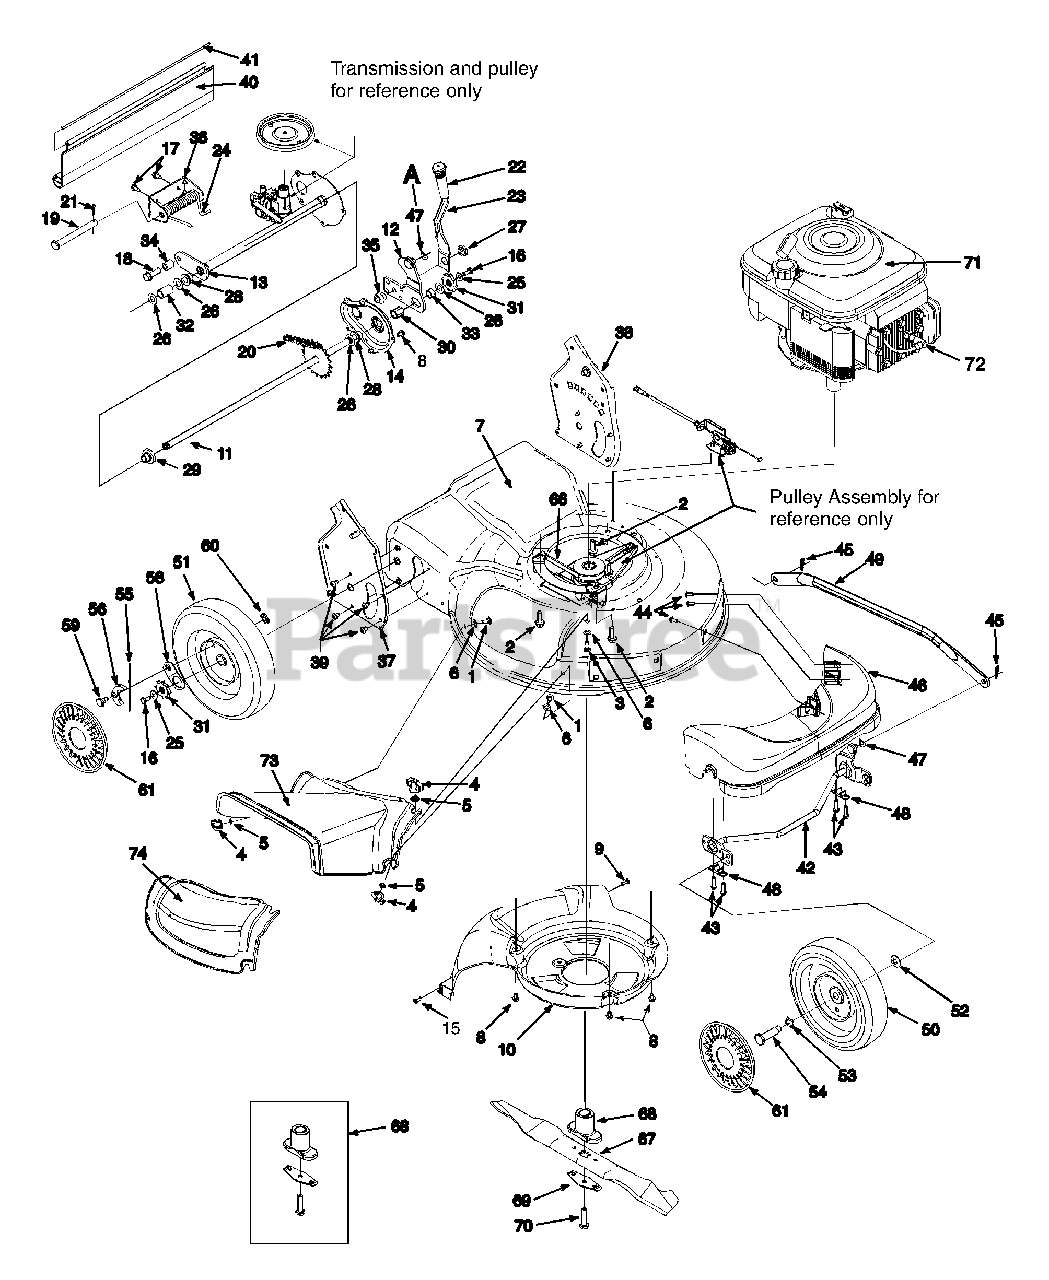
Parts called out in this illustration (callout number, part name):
1	Scr. Carr. 1/4-20 x .62
2	Scr. TT:3/8-18:1.00
3	Scr. 1/4-20 x .750
4	Wing Nut 1/4-20
5	Nut, Push .25 I.D. x .50 O.D.
6	Wash. Fl. .334 I.D.x .62 x.03
8	Scr. TT. 1/4-20 x .375
10	Baffle
11	Rear Axle Ass'y
16	Cap Screw HH 1/4-20 x .620
17	Scr., AB 1/4-14 x .825
18	Scr., 3/8 116 x .25
19	Clevis Pin .50 Dia. x 4.82 Lg.
20	Chain-Endls. #48 .500P x 24L
21	Cotter Pin .1250.D. x .75
24	Torsion Spring
25	Bell Wash. .285 x .75 x .082
26	Fl. Wash. .508 I.D. 1.000 x.020
27	Shoulder Nut .825 Dia. x .165
28	Hx.Flg. Brg. .506 I.D. x .590 L.
29	Hx.Flg. Brg. .506 I.D. x.715 L.
30	Hx. Slv. Brg. .504 I.D. x .830 L.
31	Wheel Rachet
32	Spacer .550 I.D. x .750 O.D.
33	Spacer .51 .D. x .70 O.D. x 38
34	Spacer .385 x .624 x .700
35	Shld. Spacer .385 I.D. X .715
38	Handle Brkt. Assembly L.H.
39	Scr. AB 1/4-14 x .500
40	Trail Shield
41	Trail Shield Wire
42	Fr. Axle Ass'y.
43	Hx Scr. Wash Hd. Hi. - Lo.
44	Scr. Torx, Truss Hi. - Lo.
45	Cotter Pin .072 x 1.12 Lg.
46	Fr. Axle Cover
47	Bowed Washer
48	Bush. Block .505 Dia. x .62
49	Control Arm
50	Wheel 8 x 2 Link Gray
51	Wheel 9 x 2 Link Gray, Sleeve
52	Spr. Wash. .401 x .870 x .063
53	Wave Wash .510 x .750 x .017
54	Shldr Scr .498 x 1.445 x 3/8-16
55	Spring, Ratchet, Plastic
58	Ratchet Pawl Plate
59	Hubcap - Gray
60	Top Lock Tab Weld Nut 1/4-20
61	Hubcap - Gray
66	Belt
67	21" Mulching Blade
68	Blade Adapter Kit
69	Blade Bell Support
70	Hex Bolt 3/8-24 x 2.5" Lg.
71	Engine
72	Spark Plug Insulator
73	Side Discharge Chute
74	Mulch Cover
